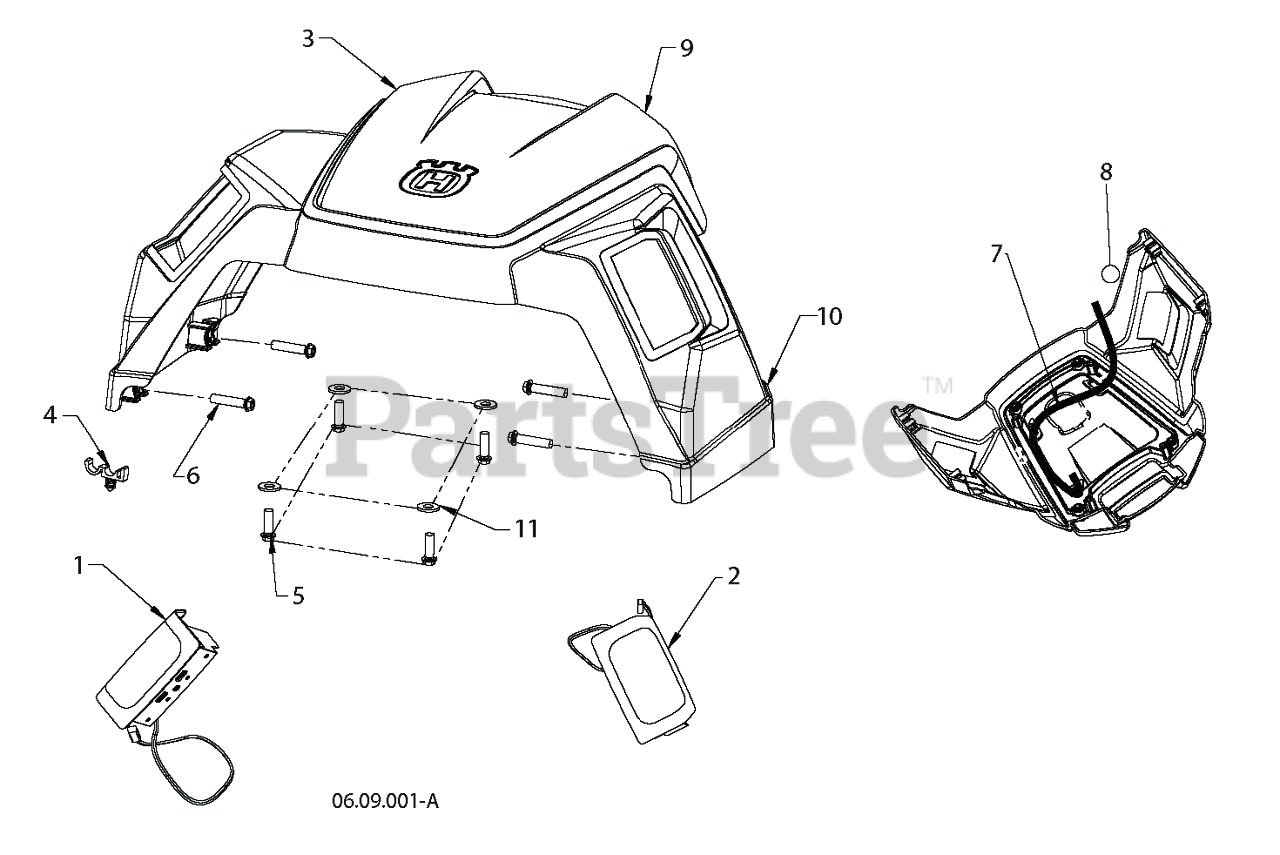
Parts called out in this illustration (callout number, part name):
1	RP SUBASM.RH.LED.SGL.STAGE.SNO
2	SUBASM.LH.LED.SINGLE.STAGE.SNO
3	CONTROL.SHROUD.SNOW
5	SCREW.HX.13X.750
6	SCREW.HWH.13-16X1.12
7	HARNESS.LED
8	HARNESS.LED.ST.SNOW
9	SUBASM.CONTROL.SHROUD
10	COVER.HANDLE.LG.SHROUD
11	WASHER
